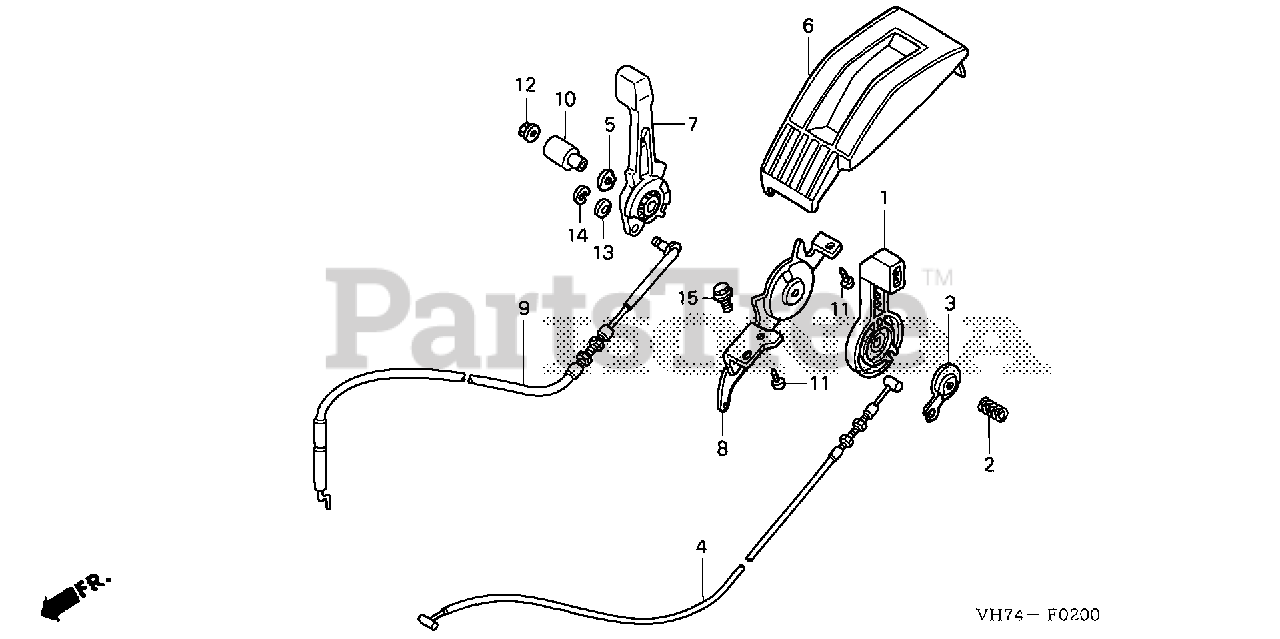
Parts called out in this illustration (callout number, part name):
1	LEVER, THROTTLE
2	SPRING, THROTTLE LEVER
3	SEAT, SPRING
4	CABLE, THROTTLE
5	WASHER, WAVE (11MM)
6	COVER, CONTROL
7	LEVER, CHANGE
8	STOPPER, LEVER
9	CABLE, CHANGE
10	COLLAR, CHANGE LEVER
11	SCREW, TAPPING (5X12)
12	NUT, FLANGE (6MM)
13	WASHER, PLAIN (6MM)
14	E-RING (5MM)
15	BOLT, FLANGE (6X10)
